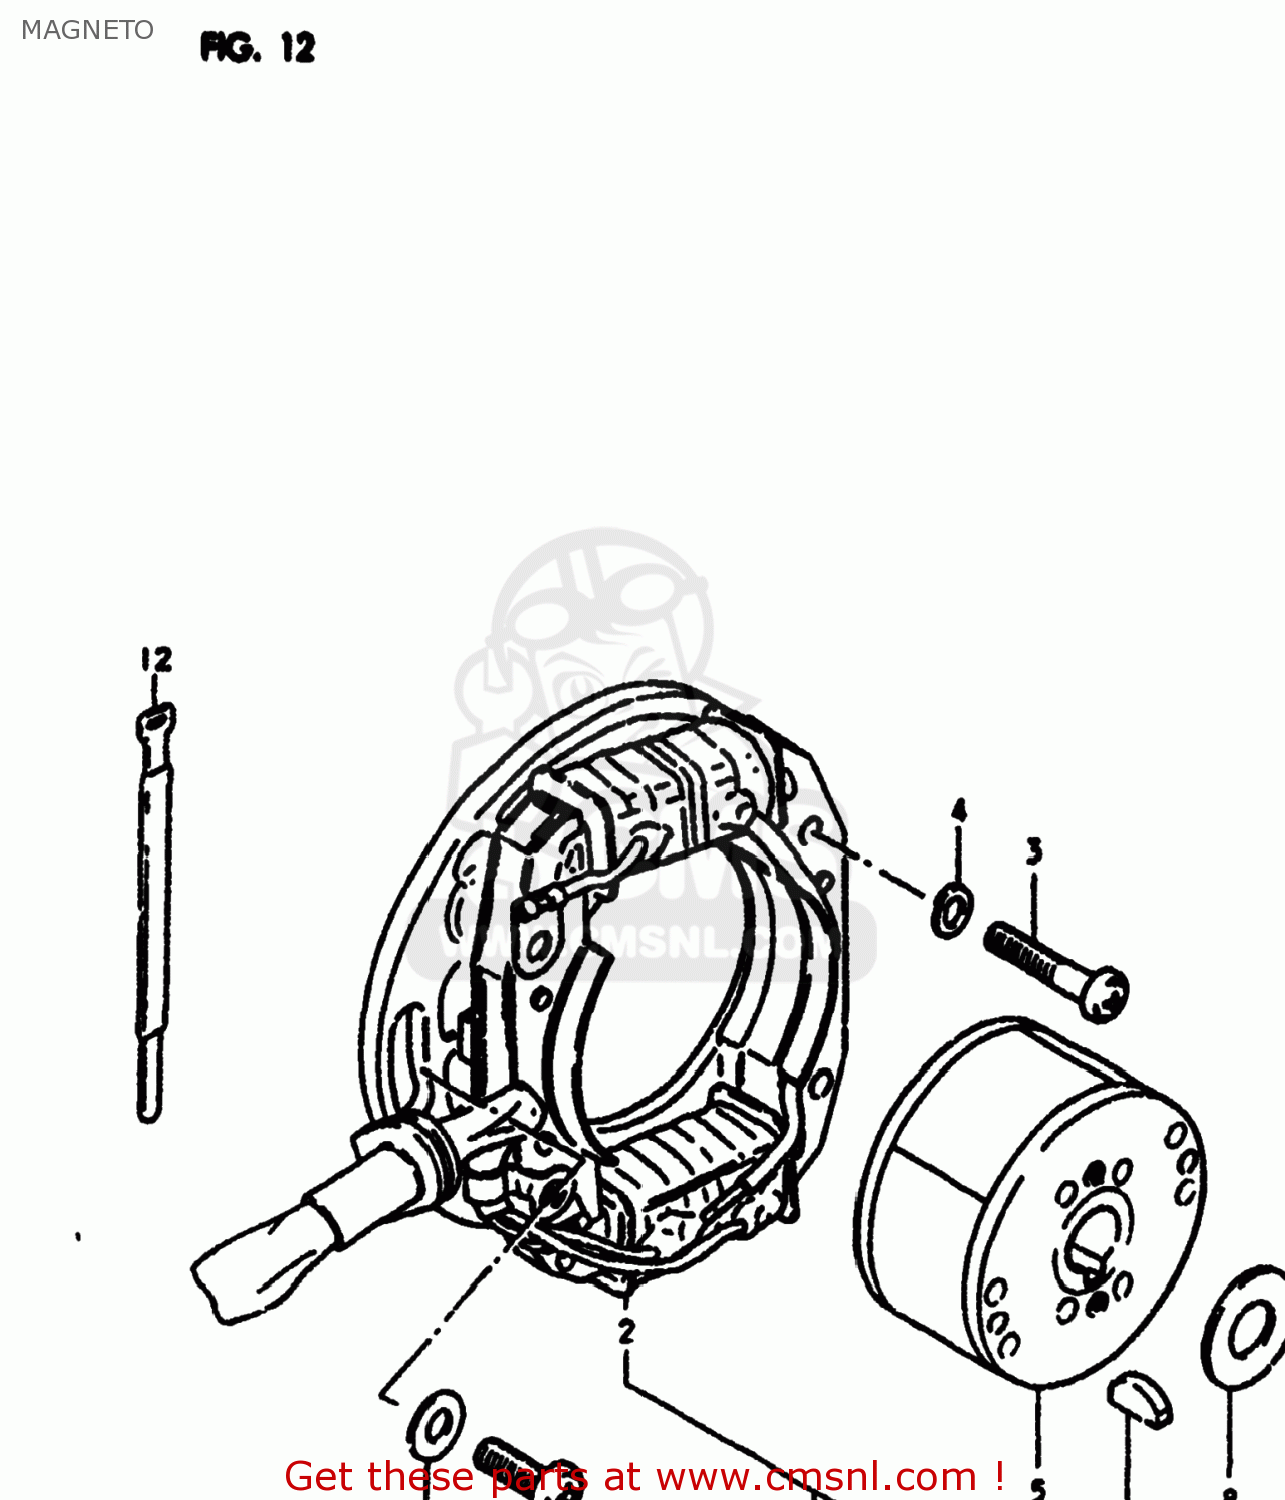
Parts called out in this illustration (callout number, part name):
1	MAGNETO ASSEMBLY
2	STATOR ASSEMBLY
3	SCREW
4	LOCK WASHER
5	ROTOR ASSEMBLY
6	NUT (10MM)
7	LOCK WASHER
8	WASHER
9	SCREW
10	WASHER
11	KEY 4MM
12	CLAMP
